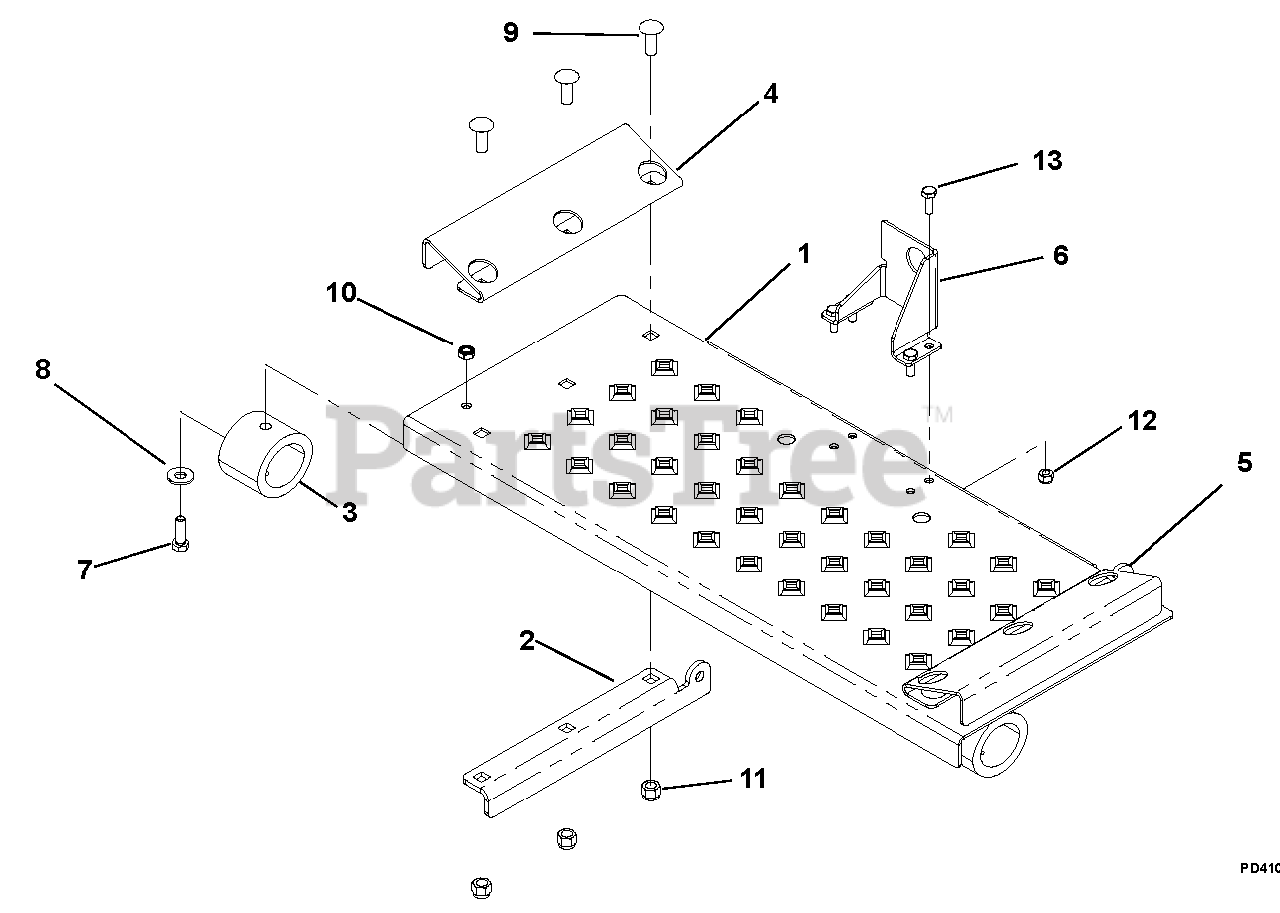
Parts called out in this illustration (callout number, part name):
1	Plate, Platform
2	Plate, Platform Tab RH
3	Bumper, Miner GBR-6
4	Wedge, Platform
5	Plate, Platform Tab LH
6	Anchor, OPC
7	Bolt, Hex .31-18 x 1.00 Grade 5
8	Washer, Flat, Steel .38 x .875 x .083
9	Bolt, Round Head Square Neck .38 x 1.00
10	Locknut, .312-18 Nyloc
11	Locknut, .38-16 Nyloc
12	Locknut, .25-20 Nyloc
13	Bolt, .25-20 x .750 Hex 5
